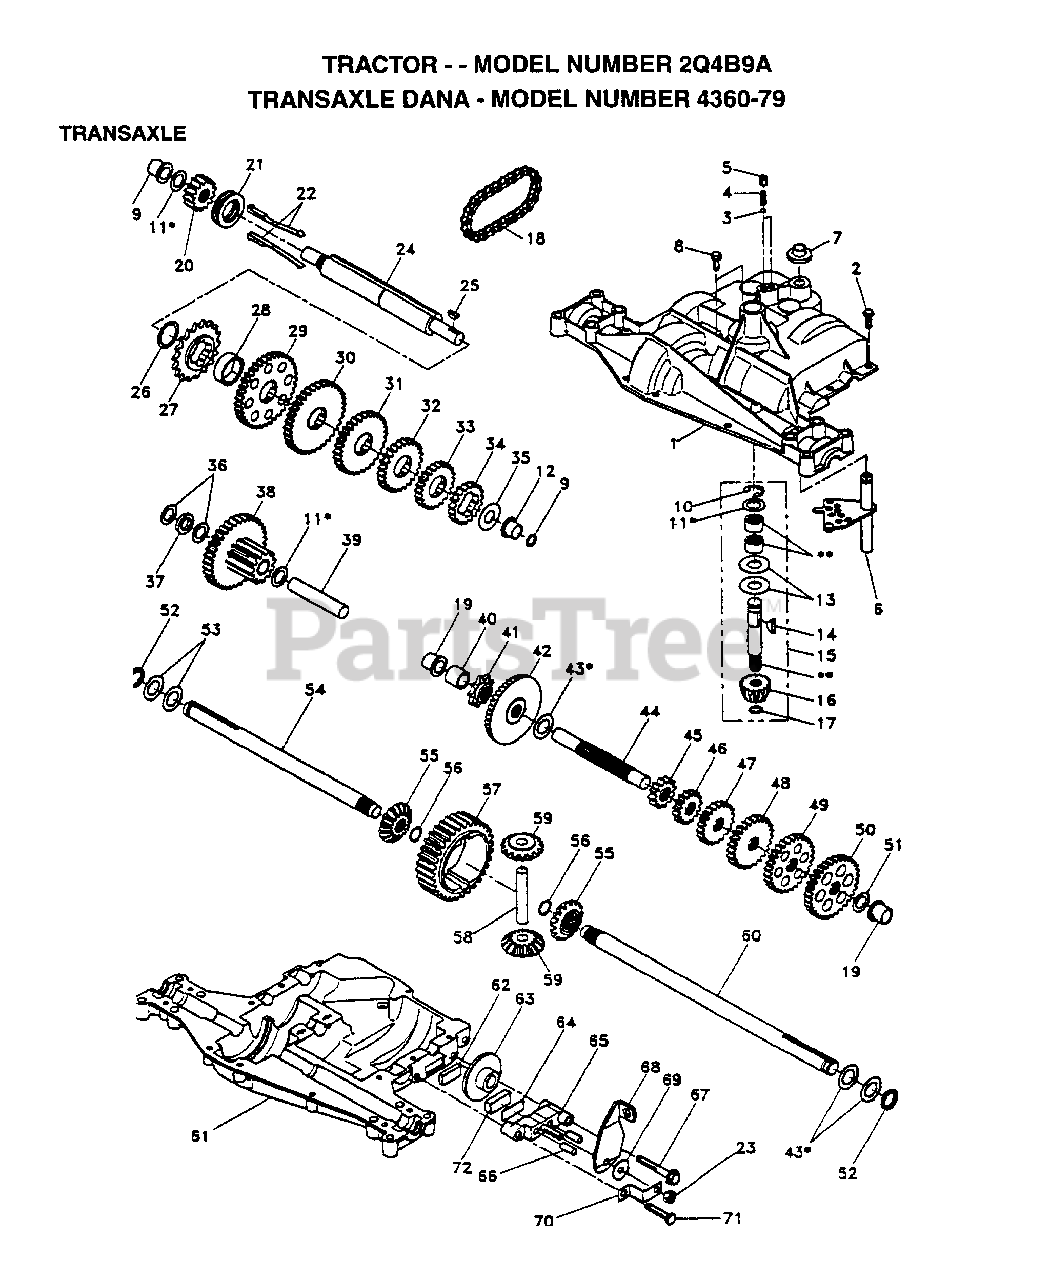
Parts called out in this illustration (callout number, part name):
1	HOUSING UPPER TRN
4	"SPRING, DETENT LT"
5	"SCREW, SET LT"
6	KIT SHIFTER ASM
7	SHIFTER BOOT
8	SCREW TAP W/SEAL
9	SQUARE RING
11	ASM KIT SHIM 4689
12	BEARING FLAN-DANA
13	WASHER T
14	KEY WOODRUFF-DANA
15	AS KIT INPUT SHFT
16	PINION 14T T
17	"RING,RETAINING LT"
18	"CHAIN,24 PTCH LT"
19	BEARING.FLNG.5510
20	GEAR SPUR 14 TTH
21	COLLAR CLUTCH
22	ASM KIT CLTCH KEY
23	NUT.LOCK.5/16-24
24	SHAFT INTERM DANA
25	WOODRUFF KEY
26	"RING,RETAINING LT"
27	SPROCKET 18T T
28	SPACER YT
29	GEAR SPUR 37 TTH
30	GEAR SPUR 35 TTH
32	GEAR 25T LT
33	GEAR SPUR 22 TT
34	SPUR GEAR 19T
35	"WASHER, PLAIN LT"
36	WASHER 025
37	SPACER
38	ASSM GEAR COMB
39	SHAFT IDLER
40	SPACER T
41	SPROCKET 9T LT
43	ASM KIT SHIM
44	SHAFT T
45	GEAR SPUR 12 TTH
46	GEAR SPUR 15 TTH
48	"GEAR, SPUR 25T LT"
49	GEAR 28T T
50	"GEAR, SPUR 31T LT"
51	WASHER 060
52	NEOPRENE WASHER
53	WASHER 031
55	GEAR 15T T
56	"RING,RETAINING LT"
58	SHAFT T
59	GEAR 1ST T
61	HOUSING LOWER TNS
62	PUCK T
63	BRAKE DISC. T
64	SPACER LT
66	PIN T
69	WASHER LT
71	"SCREW, TAPPING LT"
72	PUCK T
